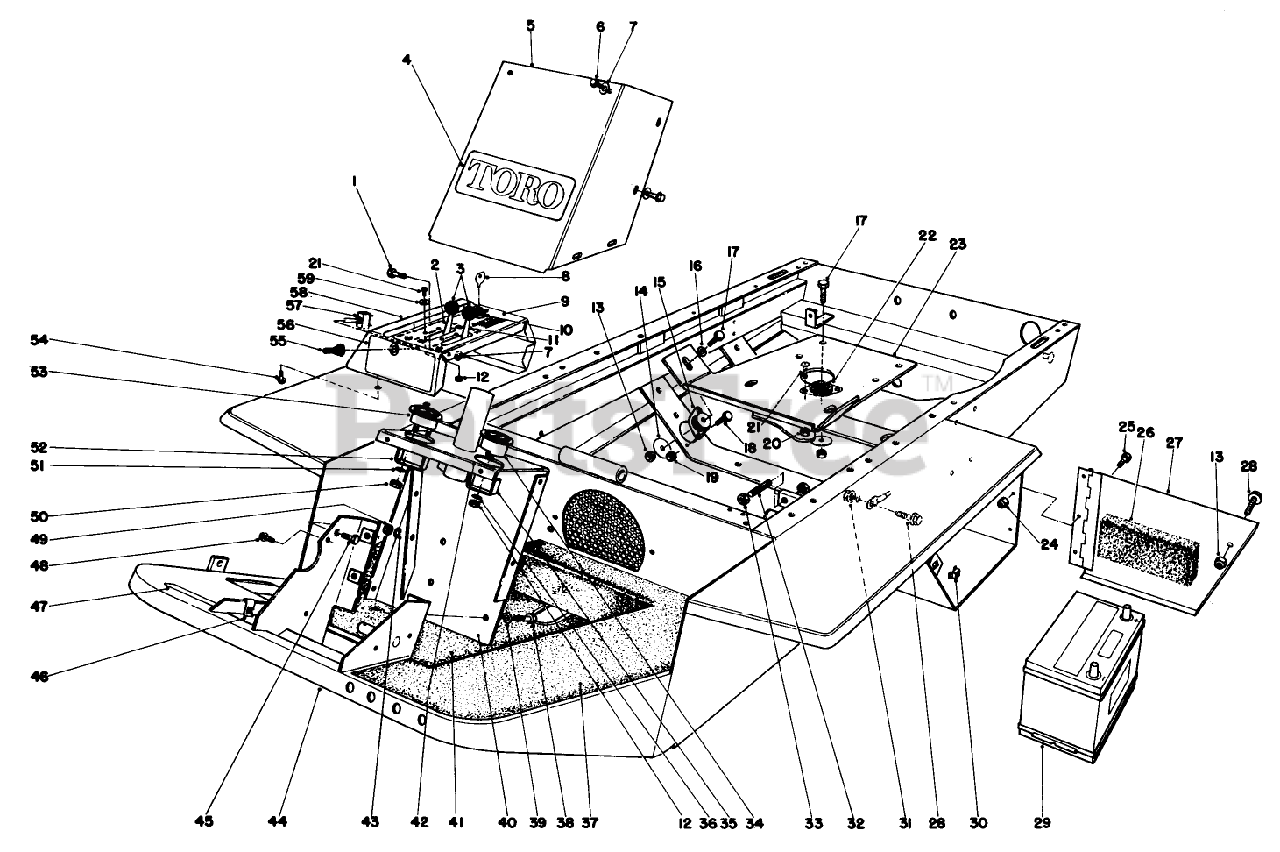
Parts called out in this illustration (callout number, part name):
1	SCREW-HH
2	CHOKE CONTROL
6	SCREW THD 1/4 20 5/8
7	WASHER-FLAT
10	SWITCH
11	THROTTLE CONTROL
12	NUT-HEX
13	NUT-LOCK, NI
14	WASHER
15	ENGINE RUBBER MT
16	WASHER-FLAT
17	SCREW-HH
18	SCREW-HH
19	NUT-LOCK, NI
20	NUT-LOCK, NI
21	SCREW-HH
22	RUBBER MOUNT
24	NUT-LOCK, NI
25	SCREW-HH
26	BATT BOX FOAM
28	SCREW-HHF
29	Battery Assy.
31	NUT-HHF, WHIZ
33	NUT-JAM
34	HOUR METER
35	BRACKET
36	WASHER-LOCK, INT
37	NON SKID (TUNNEL)
38	SCREW-HH
39	SCREW-HH
41	NON-SKID-FLOOR
43	WASHER-LOCK
44	FRAME ASM
45	SCREW-HH
48	SCREW-HWH
49	NUT-HEX
50	NUT-HEX
51	WASHER-FLAT
52	MTG CLAMP F/W GUAGE
54	SCREW-HWHTF
55	BOOT-SWITCH
56	BY-PASS DECAL
57	SWITCH & BOOT ASM
59	WASHER-LOCK
